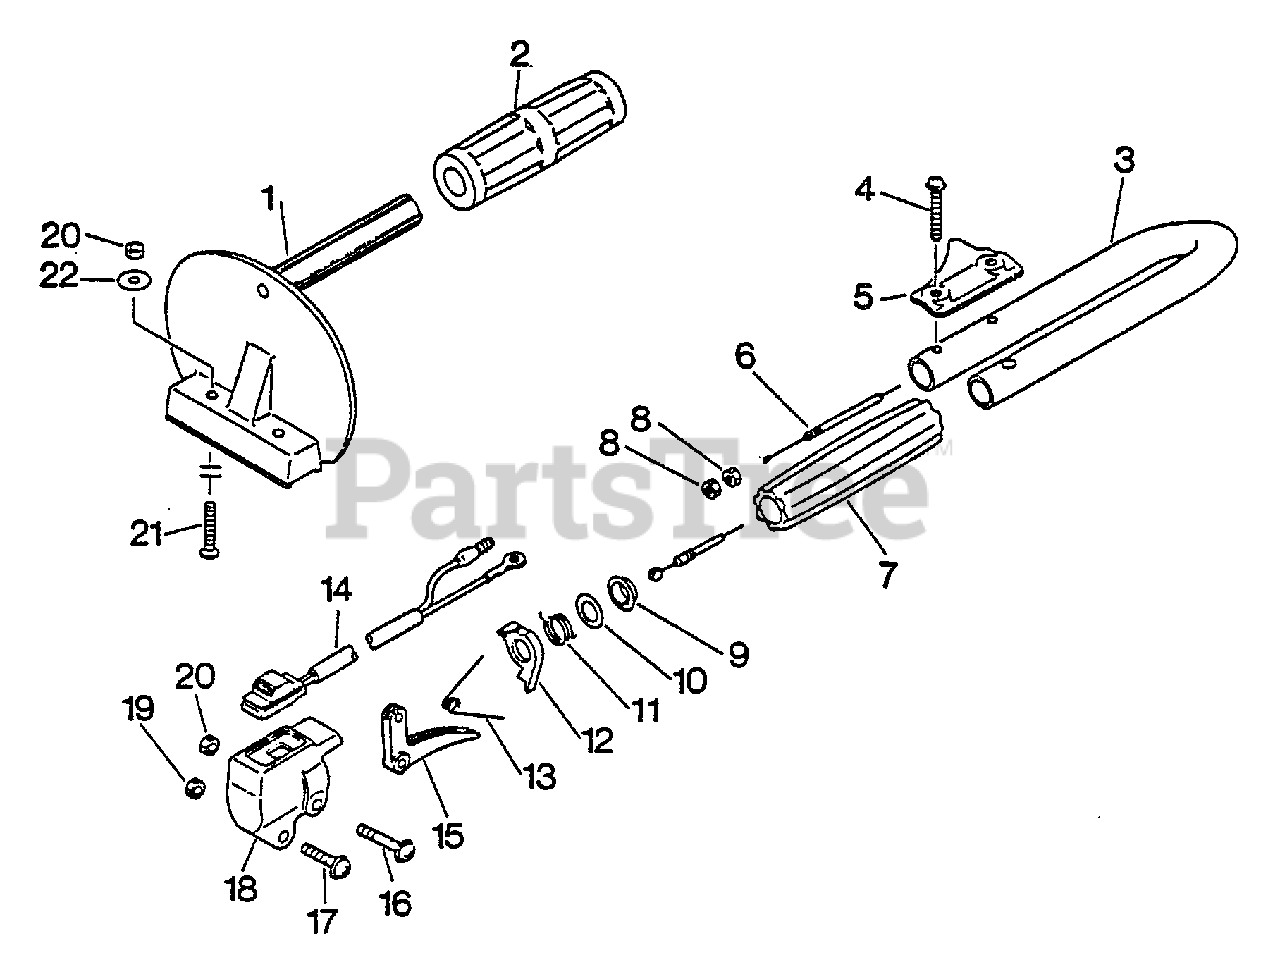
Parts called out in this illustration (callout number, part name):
1	HANDLE, FRONT
3	HANDLE - REAR
4	SCREW 5×35
5	BRACKET, HANDLE
6	CABLE, THROTTLE
10	SPACER
11	SPRING, THROTTLE LOCK
12	LOCKOUT, TRIGGER
15	TRIGGER, THROTTLE
17	SCREW 5×28
18	BRACKET, THROTTLE
19	NUT M5
20	LOCKNUT - 5
21	SCREW 5×30
22	WASHER 5.5×18×1
